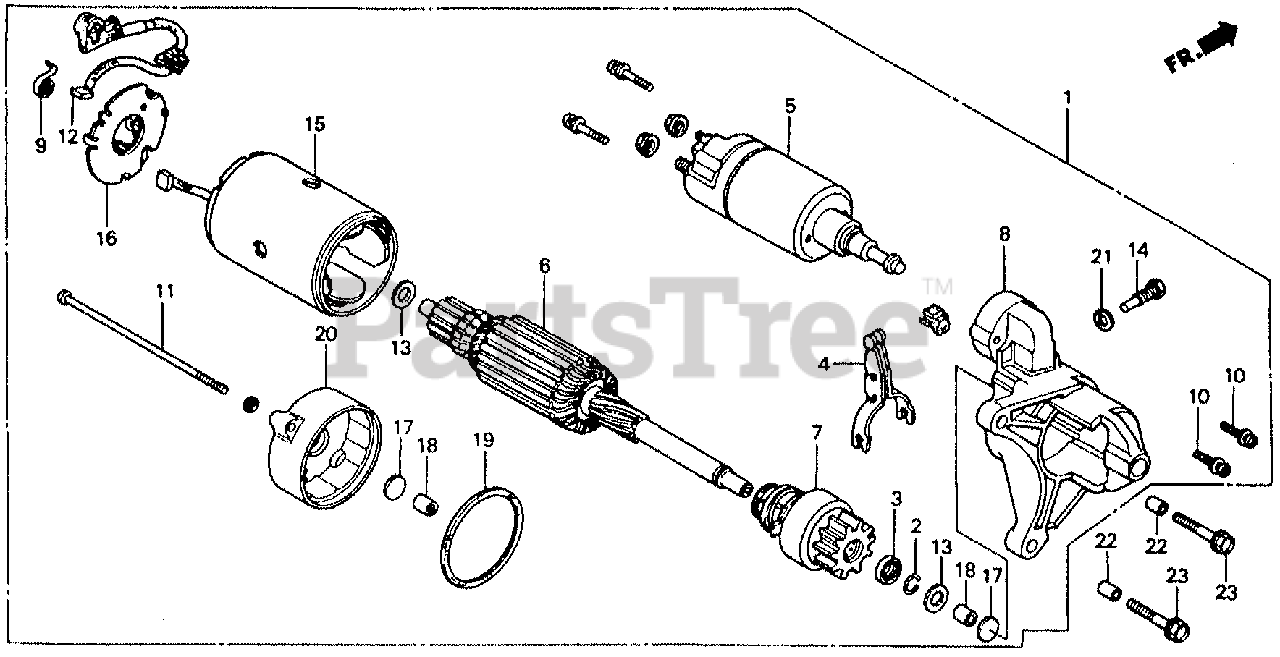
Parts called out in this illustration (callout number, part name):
1	MOTOR ASSY., STARTER
2	RING, SNAP (NOT AVAILABLE)
3	COLLAR, CLUTCH STOP
4	LEVER, PINION (NOT AVAILABLE)
5	SWITCH, MAGNETIC
6	ARMATURE
7	PINION
8	CASE, GEAR
9	SPRING, BRUSH
10	SCREW, MAGNETIC SWITCH SETTING
11	BOLT, THROUGH
12	BRUSH
13	WASHER
14	SCREW, POLE CORE SETTING
15	COIL, FIELD
16	HOLDER, BRUSH
17	COVER, BEARING
18	BUSH, BEARING
19	GASKET, RUBBER PLATE
20	COVER, RR.
21	WASHER, SPRING (8MM)
22	PIN A, DOWEL (10X16)
23	BOLT, FLANGE (8X35)
